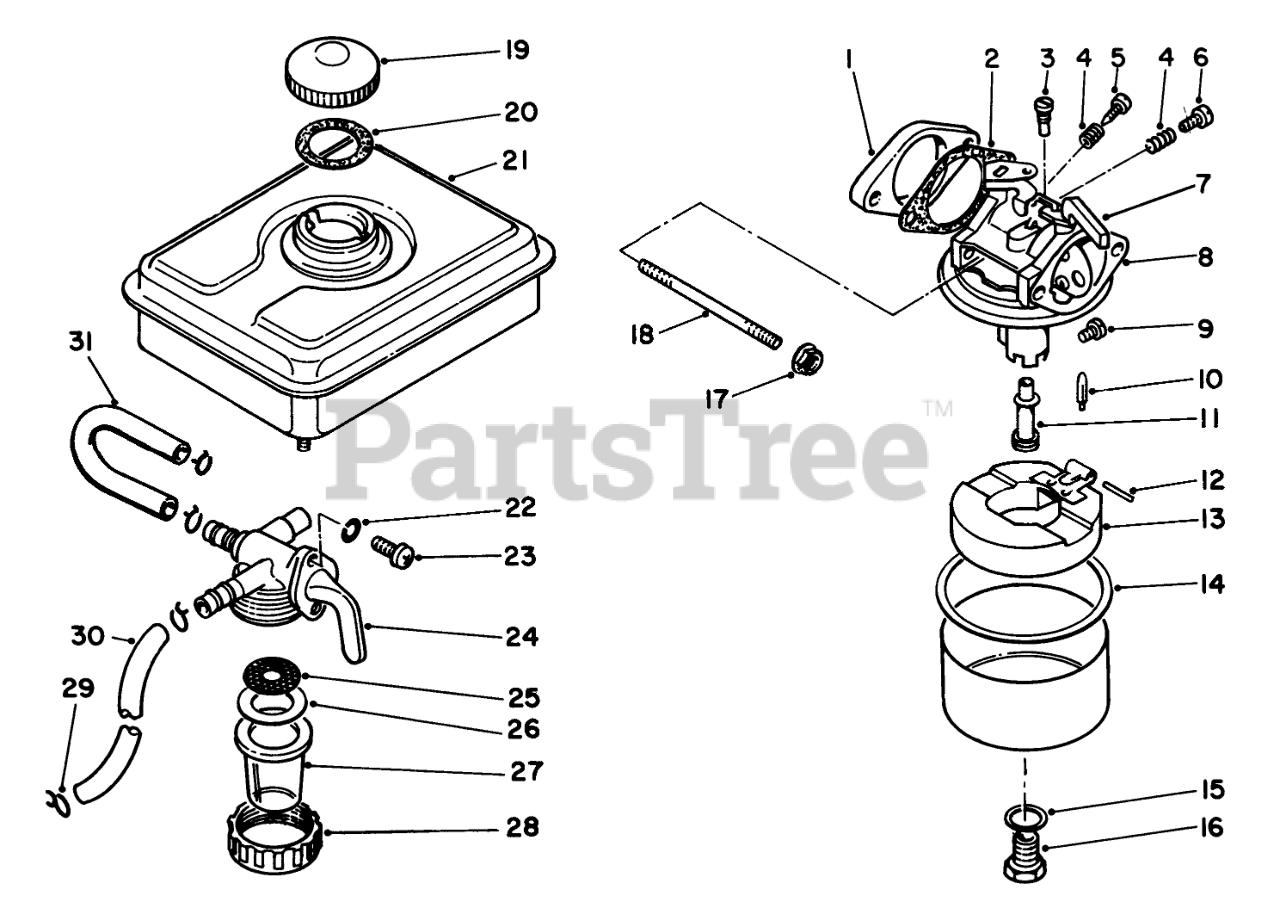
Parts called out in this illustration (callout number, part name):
1	INSULATOR
2	GASKET
3	PILOT JET
4	SPRING
5	ADJUSTER
6	SCREW
7	CHOKE SHAFT ASM
8	Carburetor Assembly (Incl. Ref. #9-16)
9	MAIN JET
10	NEEDLE VALVE
11	NOZZLE
12	Pin
13	FLOAT
14	GASKET
15	GASKET
16	Bolt
18	Stud Bolt
20	GASKET
21	Tank-Fuel
22	Lockwasher
23	Screw
24	Petcock Assembly (Incl. Ref. #25-28)
25	FILTER
26	GASKET
